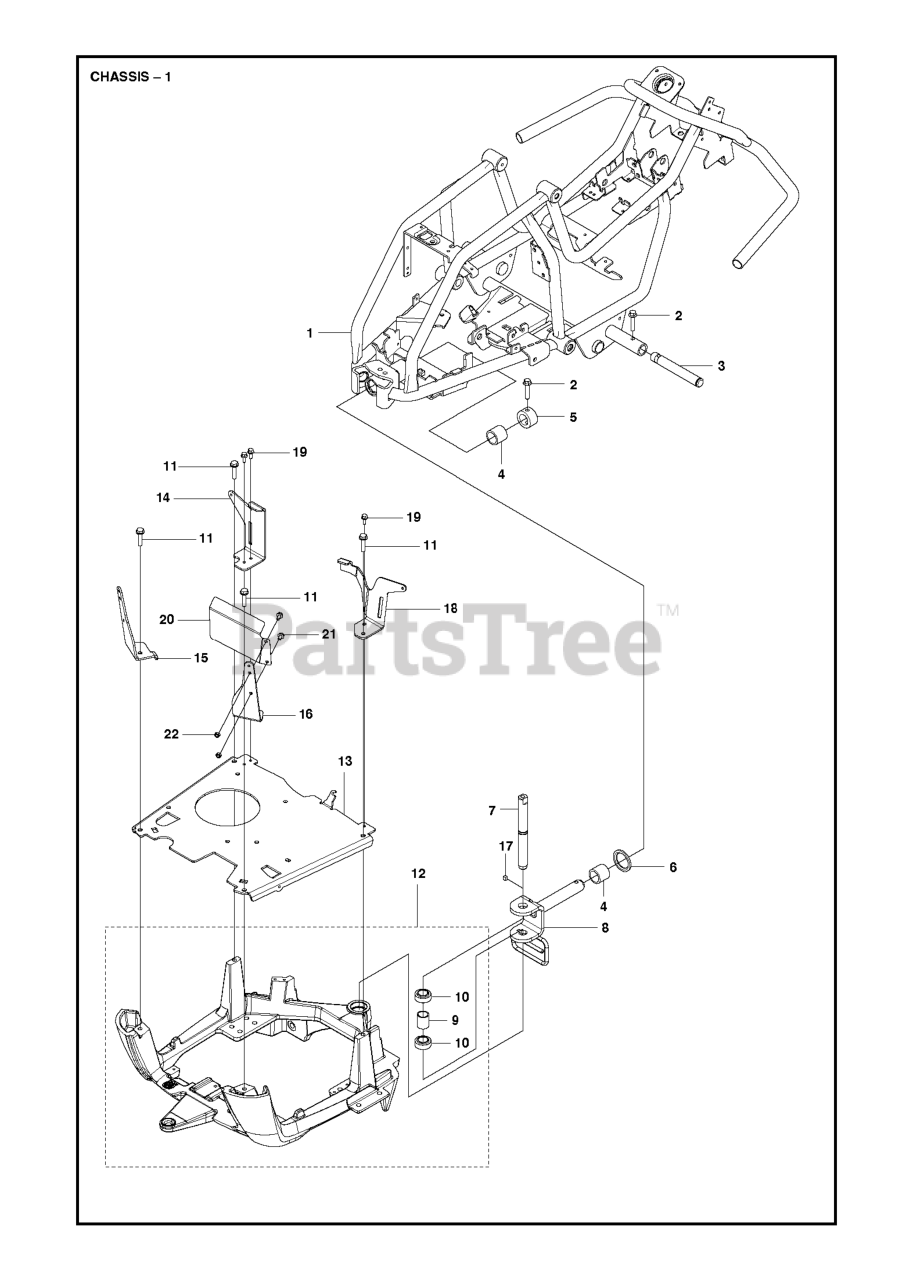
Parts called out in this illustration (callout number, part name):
1	FRAME FRONT ASSY
2	BOLT FLANGE - M8X40\
3	WHEEL AXLE
4	BUSHING
5	STOP SLEEVE
8	SWING AXLE
11	SCREW EHHFM
19	SCREW
21	SCREW EHHFM
22	LOCKNUT M6
